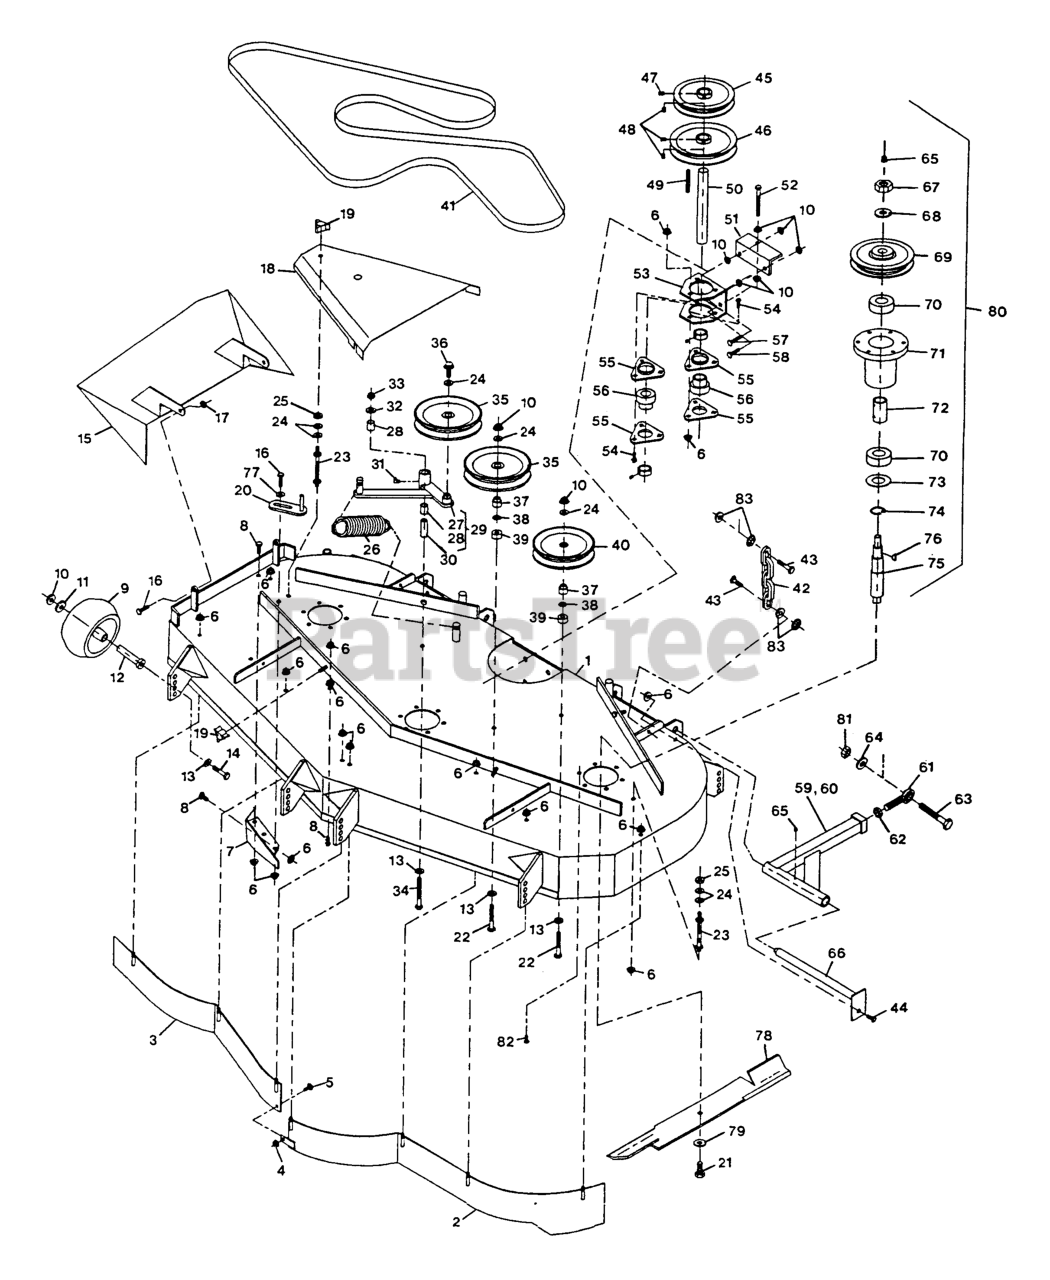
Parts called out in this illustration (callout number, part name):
3	WLD,RH BAFFLE
5	BOLT-CARR
7	WLD,BAFFLE DISCHARGE
9	ROLLER-SCALP, ANTI
12	BUSHING-ROLLER
18	SHIELD,BELT
19	KNOB-3 PRONG
20	GUIDE-BELT
23	STUD-SHIELD, BELT (SHORT)
28	SLEEVE-BEARING
30	BUSHING
37	BUSHING-IDLER
39	SPACER
39	WASHER
40	PULLEY-IDLER
41	BELT,BLADE DRIVE
42	CHAIN-LIFT, DECK
43	SCREW-CAP, HH
45	SHEAVE,BLADE DRIVE
46	SHEAVE,SPLIT STEEL
48	SCREW-SET
49	KEY,MACH 1/4X1/4X2-5/8
50	JACKSHAFT,DECK DRIVE
53	BRACKET,JACKSHAFT
55	HOUSING-FLANGE
56	BEARING,W/COLLAR
61	BALLJOINT-SPHERICAL
66	PIN-STRUT
68	WASHER-SPRING
69	PULLEY-CAST IRON
72	SPACER,BEARING
73	SEAL,MECHANICAL DUST
74	RING,SNAP WLDS N5000-244
75	SPINDLE-OUTER BLADE
77	WASHER-SPRING
79	WASHER-SPRING
80	CUTTER HOUSING ASSY
82	SCRW,TPTTE HH
